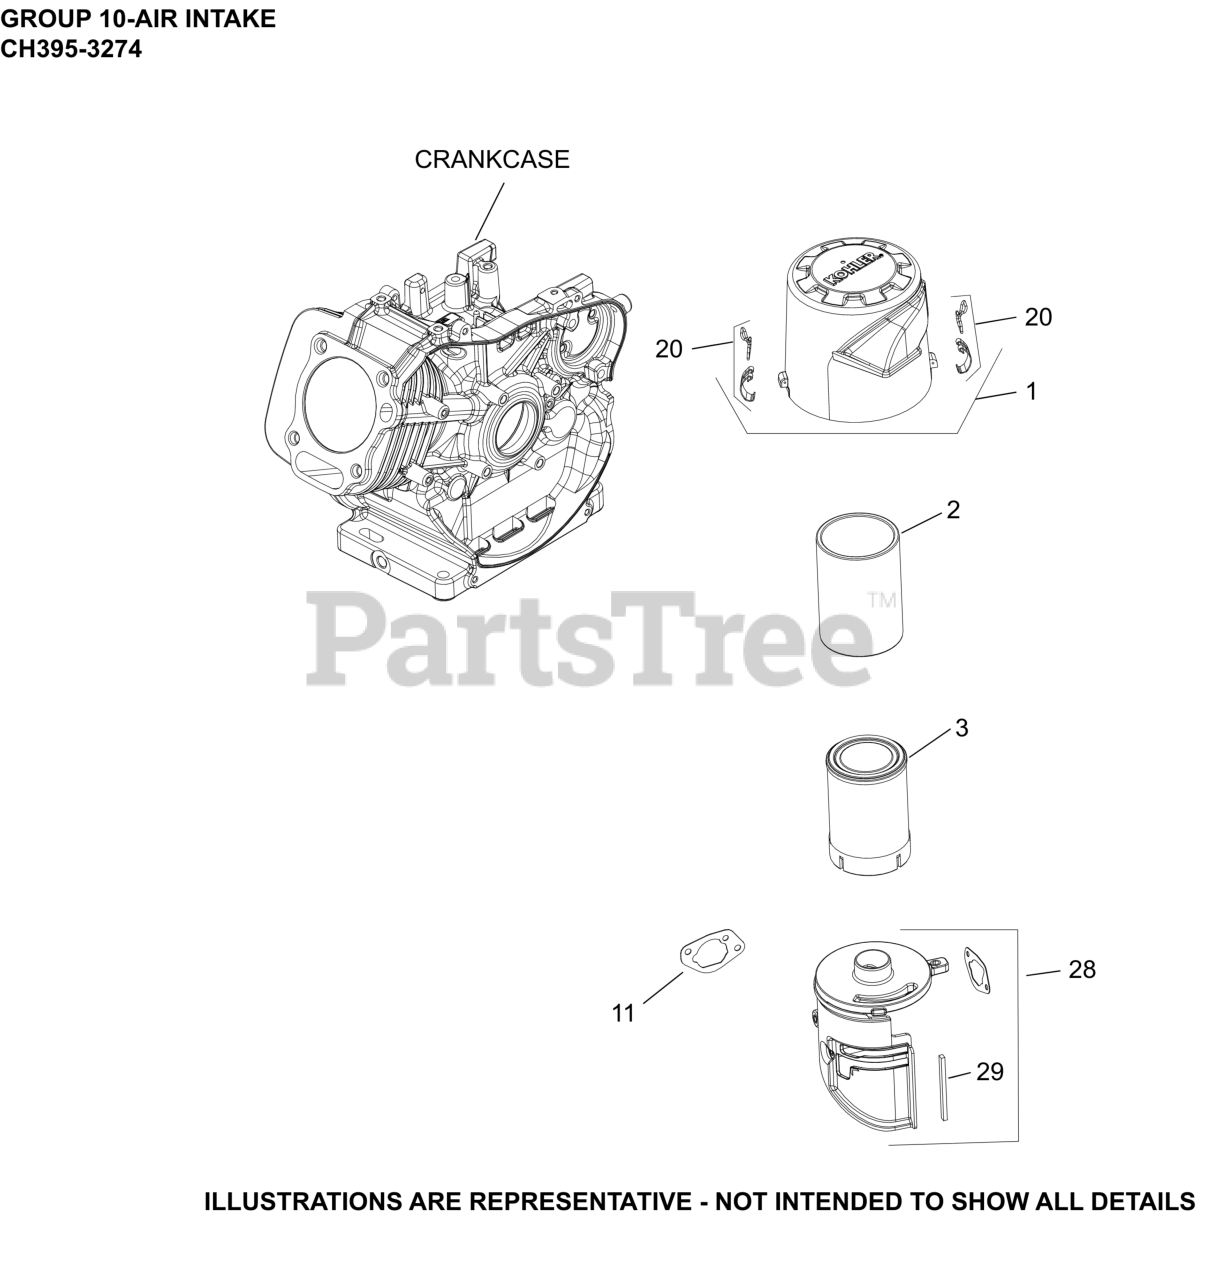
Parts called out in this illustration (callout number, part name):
1	COVER, AIR CLEANR ASSEMBLY
2	ELEMENT, PRE-CLEANER
3	ELEMENT, AIR FILTER
11	GASKET, AIR CLEANER
20	KIT, LATCH CLIP
28	KIT, AIR CLEANER BASE ASSEMBLY
